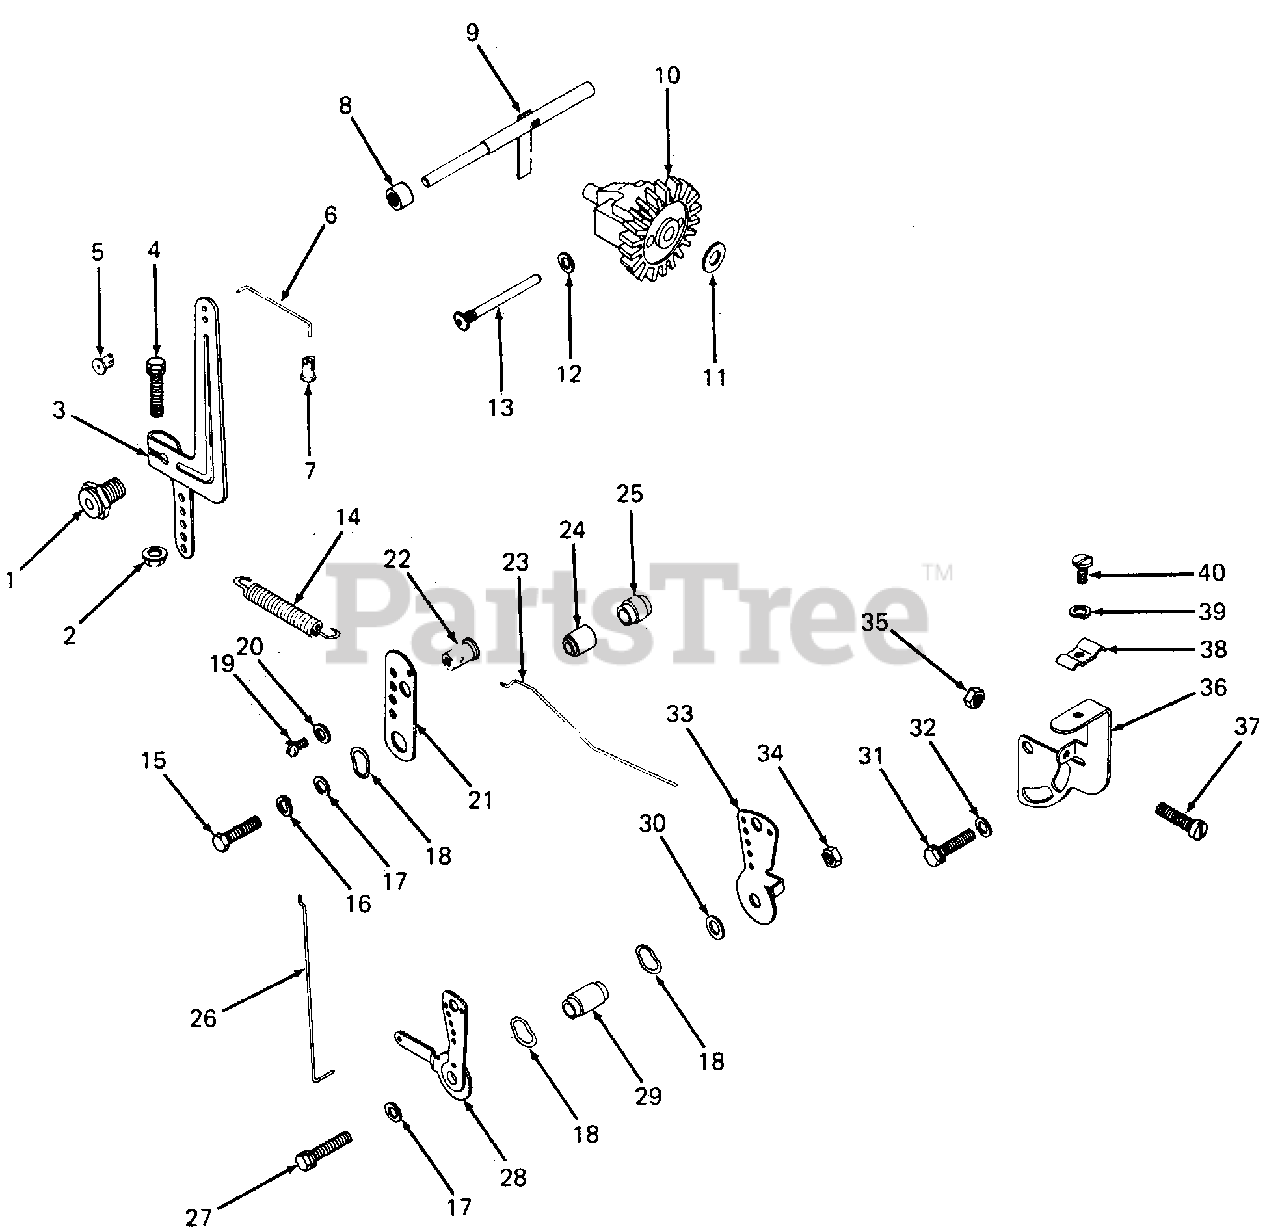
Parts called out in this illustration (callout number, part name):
1	Bushing, Governor
2	Palnut, 1/4-20
3	Lever, Governor
4	Screw, HC Sems, 1/4-20 X 1-1/4 Lg
5	Bushing, Linkage Retaining
6	Linkage, Governor
7	Bushing, Linkage Retaining
8	Spacer
9	Kit, Governor Cross Shaft
10	Kit, Governor Gear
11	Washer, Thrust
12	Washer, Plain, 1/4
13	Pin, Governor Stop
14	Spring, Governor
15	Screw, HC, 1/4-20 X 1-1/2 Lg
16	Washer, Lock, 1/4
17	Washer, Plain, 1/4
18	Washer, Wave
19	Screw, Sltd Pan Hd, #8-32 X 1/4 Lg
20	Washer, Plain, 1/4
21	Bracket, Speed Control
22	Kit, Clamp
23	Linkage, Throttle
24	Spacer
26	Linkage, Choke
27	Screw, HC Sems, 1/4-20 X 1-1/4 Lg
28	Lever, Choke Control
30	Washer, Plain, 3/8
31	Screw, HC Sems, 1/4-20 X 3/8 Lg
32	Washer, Plain, 1/4
33	Lever, Throttle Control
34	Nut, Hex, 1/4-20
35	Nut, Hex, #8-32
38	Clamp
39	Washer, Lock, #10
40	Screw, FHM, #10-24 X 1/2 Lg
